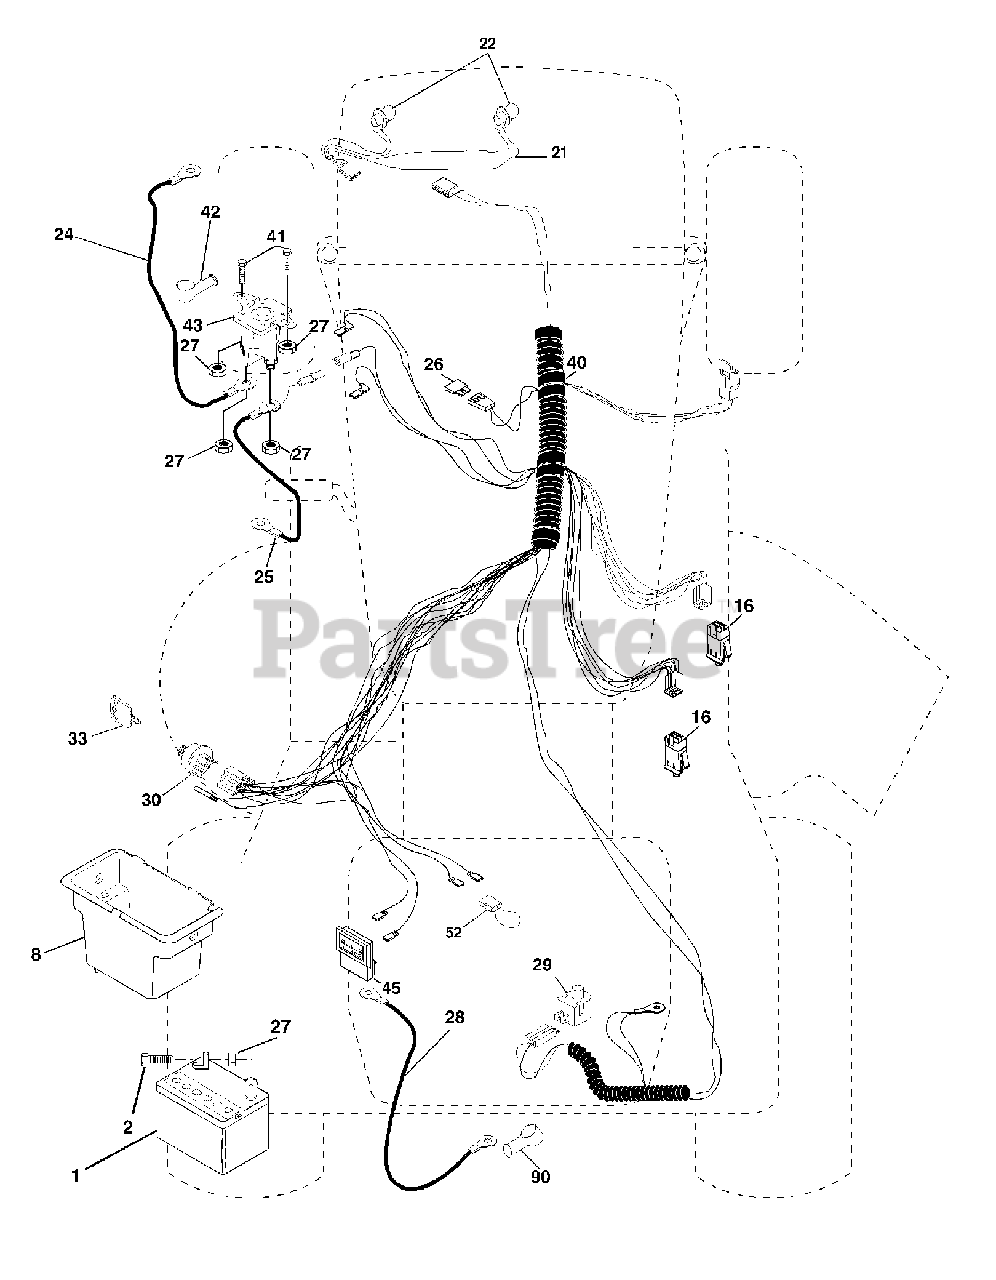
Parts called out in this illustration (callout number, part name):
1	REPL BY 532 12 38-99
2	BOLT.HEX.1/4.X.3/4.DICHROMATE
8	BOX.BATTERY.FENDER
16	SWITCH INTERLOOK PUSH-IN
21	HARNESS.ASM.LIGHT
22	LIGHTBULB
25	CABLE BATTERY
26	FUSE 20AMP
27	NUT
29	SWITCH SEAT
30	IGNITION SWITCH
33	KEY MLD GEN DELTA
40	HARNESS.IGNITION
41	BOLT
42	TERMINAL COVER
43	Solenoid Kit, .95
45	AMMETER
52	WIRE PROTECTION LOOP
90	COVER TERMINAL
